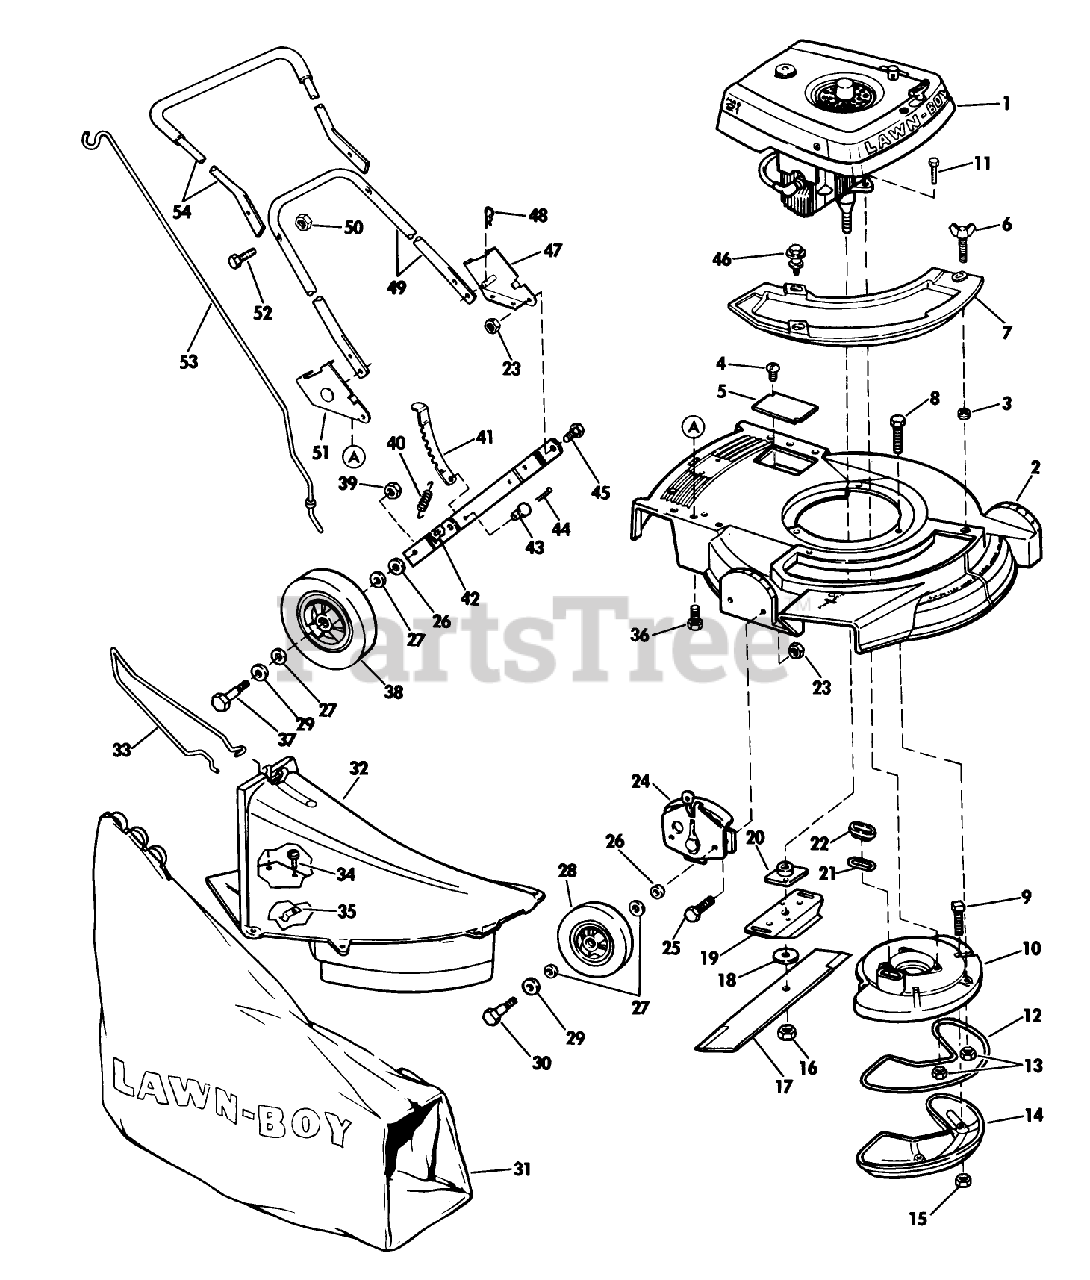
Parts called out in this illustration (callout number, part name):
6	WING SCREW LAWRE
15	LOCKNUT E
16	NUT-BLADE
20	PLATE AND COLLAR ASM
21	GASKET S
26	WASHER WROUGHT
30	BOLT WHEEL
39	LOCKNUT
40	SPRING N.A.S
45	BOLT-SHOULDER
48	HAIR PIN
53	ROD GRASSBAG
